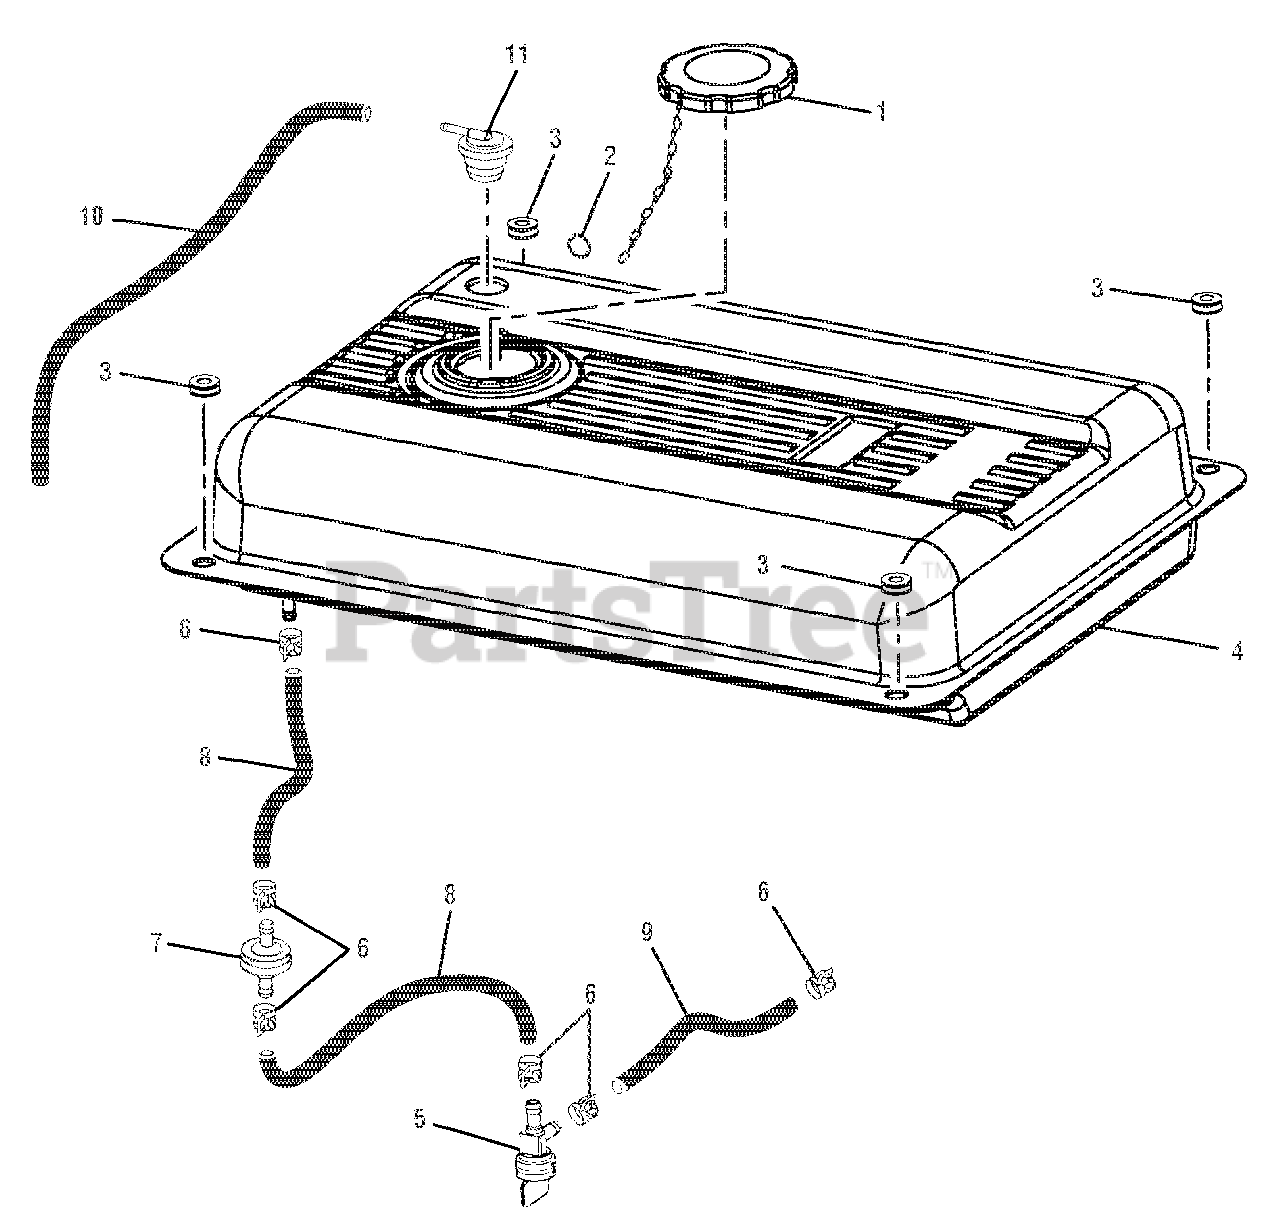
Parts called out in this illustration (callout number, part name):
1	FUEL TANK CAP
2	RING CLIP
3	BUSHING W/INSERT
4	FUEL TANK ASSEMBLY
5	FUEL VALVE
6	FUEL LINE CLAMP (1/2 IN.)
7	FUEL LINE FILTER
8	FUEL LINE
9	FUEL HOSE (1/4 IN.)
10	VAPOR HOSE
11	VAPOR VENT
